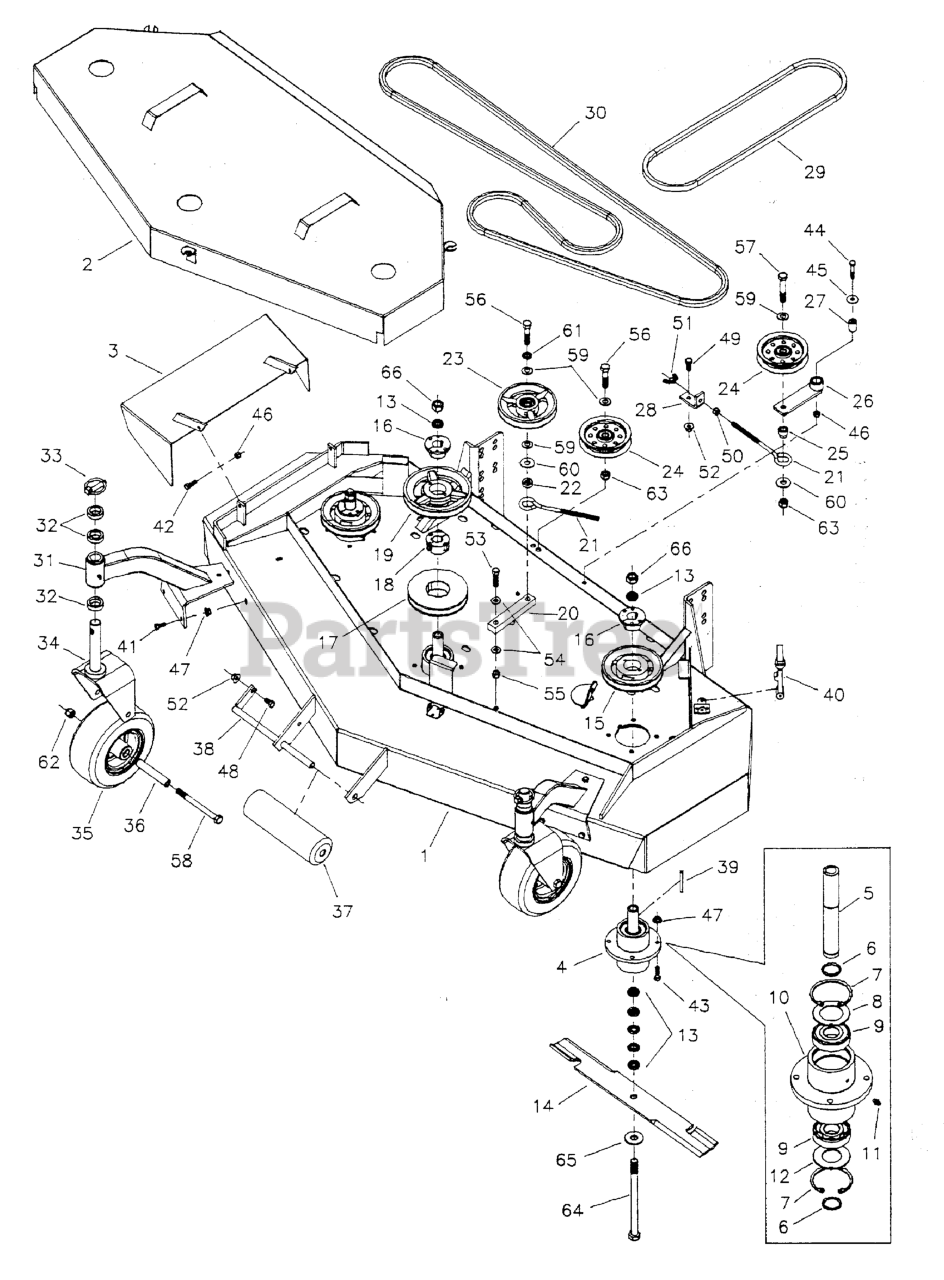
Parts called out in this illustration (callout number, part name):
1	61" MOWER HOUSING ASSEMBLY
2	61" DECK GUARD
3	CHUTE, DISCHARGE WELDMENT
4	SPINDLE ASSEMBLY, Complete
5	SPINDLE SHAFT
6	SNAP RING, External
7	SNAP RING, Internal
8	SPINDLE WASHER, Top
9	BEARING
10	SPINDLE HOUSING
11	GREASE FITTING
12	SPINDLE WASHER, Bottom
13	SPACER, .63 x 1.06 x .23
14	MOWER BLADE, 21"
15	PULLEY, Spindle
16	BUSHING, Tapered Hub
17	PULLEY, Taper Lock
18	BUSHING, Taper Lock
19	PULLEY, Spindle
20	ARM, Idler
21	EYEBOLT, 3/8" x 8"
22	SPACER, .52 X 1.00 X .38
23	IDLER PULLEY, Complete
24	PULLEY, Idler
25	INSERT, Bearing Shoulder
26	ARM, Idler
27	SPACER, .32 x .75 x 1.06
28	SPRING ANCHOR
29	BELT, Deck Drive
30	BELT, Blade Spindle
31	CASTER MOUNT, Complete
32	SPACER, 1.02 x 1.56 x .50
33	PIN, Lynch
34	YOKE, Caster
35	WHEEL & TIRE ASSEMBLY, White, 9 x 3.5 x 4, Complete
36	AXLE, Caster Wheel
37	ROLLER
39	KEY, 1/4 SQ. X 2-1/2
40	RUBBER LATCH
41	BOLT, 5/16-18 X 3/4 GD5
42	BOLT, 5/16-18 X 1 GD5 YZ
43	BOLT, 5/16-18 x 1-1/4
44	BOLT, 5/16-18 x 1-3/4
45	WASHER, 5/16" Fender
46	NUT, 5/16-18 Hex Nylon Lock
47	NUT, 5/16-18 HEX SERRATED FLANGE (LARGE)
48	BOLT, 3/8-16 X 3/4" GD5 CZ
49	BOLT, 3/8-16 X 1" GD5 CZ
50	NUT, 3/8-16 Hex
51	NUT, 3/8-16 Wing Nylon Lock
52	NUT, 3/8-16 Hex Serrated Flange
53	BOLT, 7/16-20 X 1-3/4" GD.5
54	WASHER, 7/16" SAE
55	NUT, 7/16-20 Hex Nylon Lock
56	BOLT, 1/2-20 X 2-1/4 GD5 CZ
57	BOLT, 1/2-20 x 3
58	BOLT, 1/2-13 x 5-1/2
59	WASHER, 1/2 SAE
60	WASHER, 1/2" USS
61	WASHER, 1/2" Lock
62	NUT, 1/2-13 HEX NYLON LOCK
63	NUT, Hex, Nylon Lock, 1/2-20
64	BOLT, 5/8-11 x 9-1/2
65	WASHER, 5/8" USS
66	NUT, 5/8-11 Hex
